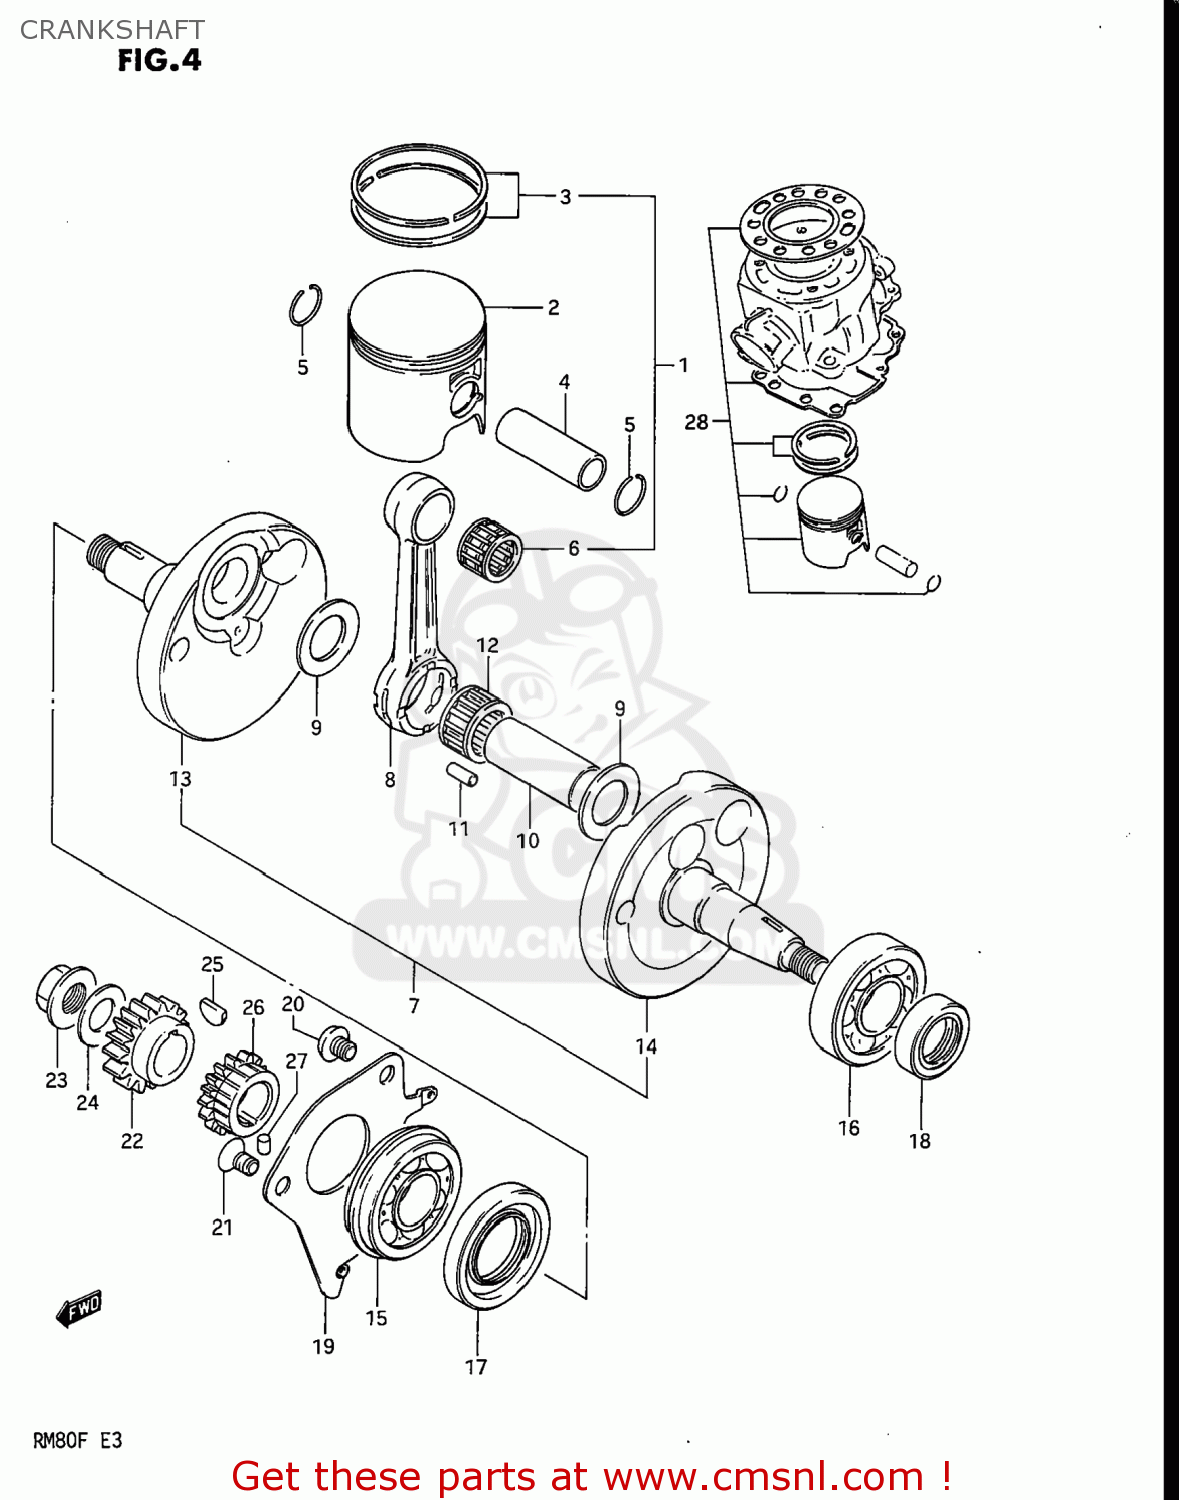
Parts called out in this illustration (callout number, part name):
1	PISTON SET (RM80XH)
2	PISTON
3	RING SET,PISTON
4	PIN,PISTON
5	RING,SNAP 14MM
6	BEARING(14X18X16)
7	CRANKSHAFT ASSEMBLY
8	CONNECTING ROD
9	WASHER
10	PIN,CRANK
11	ROLLER(3X11)
12	CAGE
13	CRANKSHAFT
14	CRANKSHAFT,LEFT
15	BEARING(20X47X14)
16	BEARING
17	SEAL,OIL(26X47X7.3)
18	SEAL,OIL(18X30X8)
19	PLATE,CRANKSHAFT BEARING
20	SCREW 6X12
21	SCREW
22	GEAR,PRIMARY DRIVE
23	NUT
24	WASHER
25	KEY
26	GEAR,WATER PUMP DRIVE
27	PIN 3X5
28	PISTON SET
